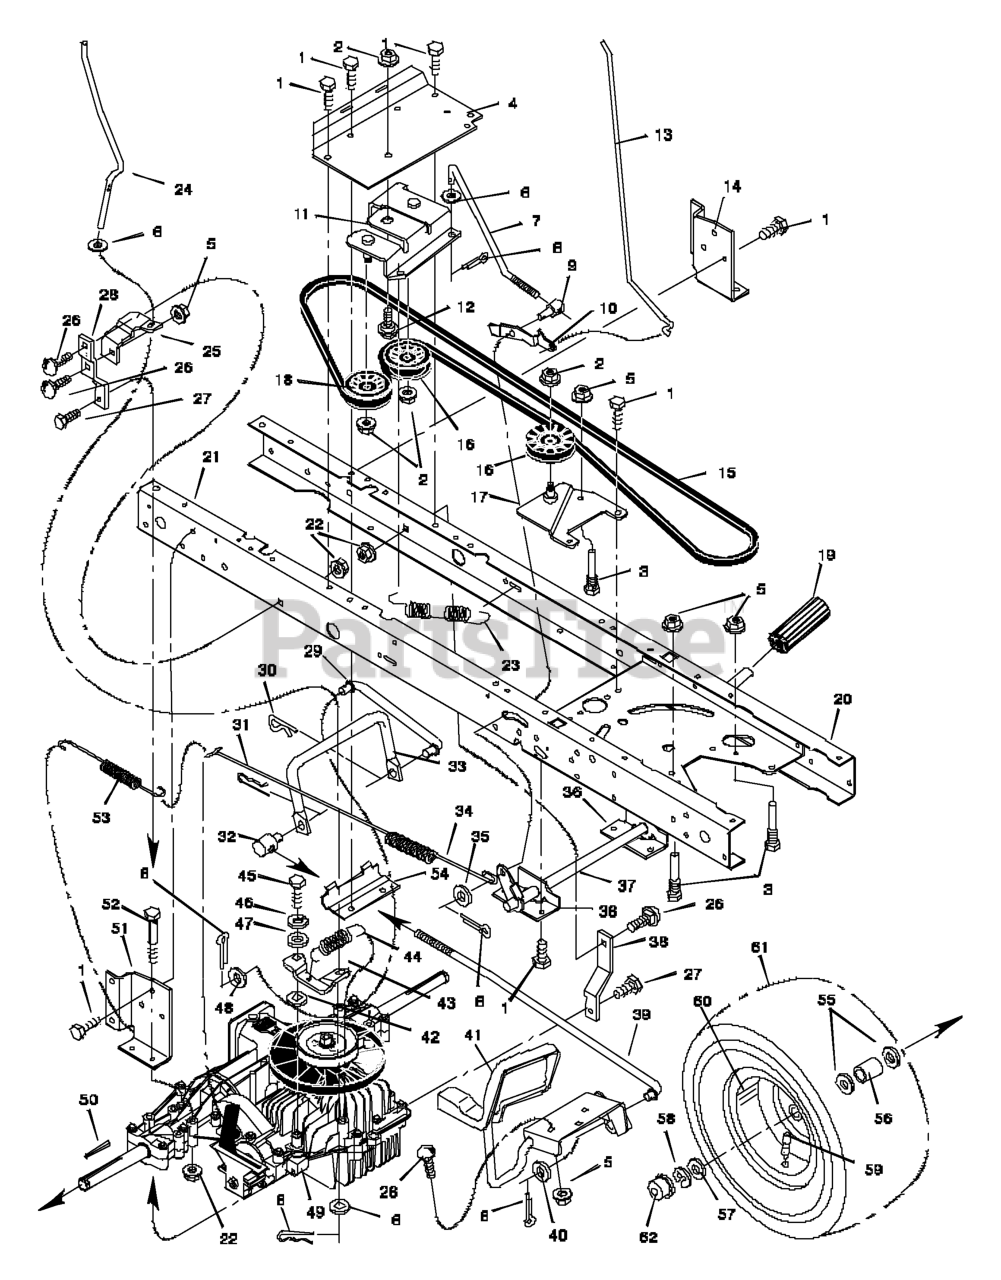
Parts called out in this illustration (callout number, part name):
2	Nut, Flange
3	Guide, Belt
4	Bracket, Idler
5	Locknut
6	Washer
7	Rod, Clutch
8	Pin, Cotter
9	Adjuster
10	Latch, Parking Brake
11	Bracket Assembly, Idler
12	Bolt, Shoulder
13	Rod, Parking Brake
14	Bracket, Transaxle
16	Pulley, Idler
17	Arm Assembly, Idler
18	Pulley, Idler
19	Pedal
20	Frame, Left
21	Frame, Right
22	Nut, Flange
23	Spring, Extension
24	Rod, Disconnect
25	Bracket, Disconnect
26	Bolt, Carriage
28	Strap, Right Torque
29	Rod, Link
30	Pin, Hair
31	Pin, Hair
32	NUT, Adjusting, 1/2-13
33	Rod, Yoke
34	Spring, Extension
35	Washer
36	Bracket, Pivot
37	Lever, Clutch/Brake
38	BRACKET, Torque Strap, LH
39	Rod, Link
41	Pedal, Speed Control
43	Arm, Disconnect
44	Spring
46	Lockwasher
48	Washer
49	Transaxle **
50	Key, Square
51	Bracket, Right Transaxle
52	Bolt
53	Spring, Extension
54	Clamp, Transaxle
56	Spacer
59	Valve Stem
60	Wheel & Tire Assembly
62	Cap, Hub
